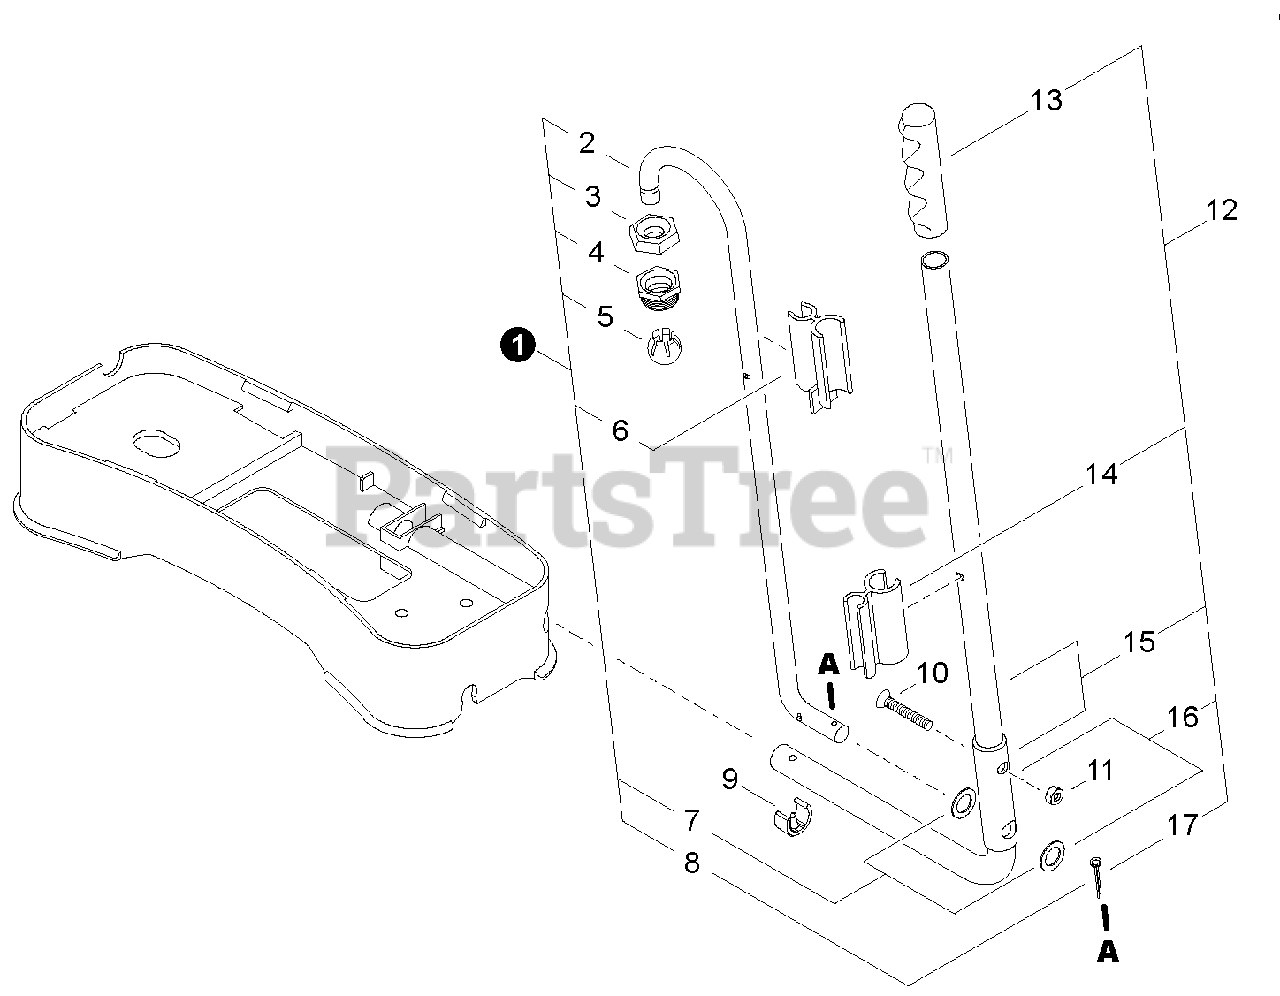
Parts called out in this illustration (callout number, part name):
1	PUMP ARM KIT
2	ARM, PUMP
3	BOOT, JOINT
4	NUT, JOINT
5	JOINT, BALL
6	CLIP, PUMP LEVER
7	WASHER
8	PIN, SPLIT
11	LOCKNUT
12	PUMP LEVER KIT
13	GRIP, LEVER
14	CLIP, WAND
15	LEVER, PUMP
16	WASHER
17	PIN, SPLIT
